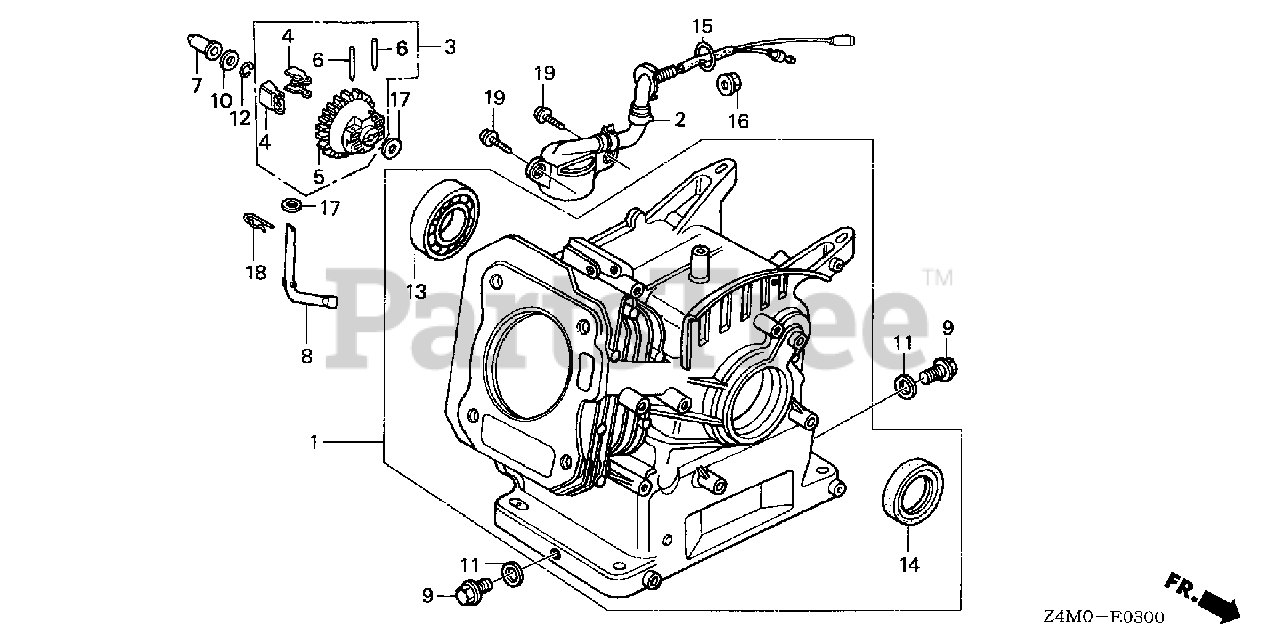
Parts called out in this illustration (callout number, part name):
1	CYLINDER ASSY. (OIL ALERT)
2	SWITCH ASSY., OIL LEVEL
3	GOVERNOR ASSY.
4	WEIGHT, GOVERNOR
5	HOLDER, GOVERNOR WEIGHT
6	PIN, GOVERNOR WEIGHT
7	SLIDER, GOVERNOR
8	SHAFT, GOVERNOR ARM
9	BOLT, DRAIN PLUG
10	WASHER, THRUST (6MM)
11	WASHER, DRAIN PLUG (10.2MM)
12	CLIP, GOVERNOR HOLDER
13	BEARING, RADIAL BALL (6205)
14	OIL SEAL (25X41X6)
15	O-RING (13.5X1.5) (ARAI)
16	NUT, FLANGE (10MM)
17	WASHER, PLAIN (6MM)
18	PIN, LOCK (8MM)
19	BOLT, FLANGE (6X12)
